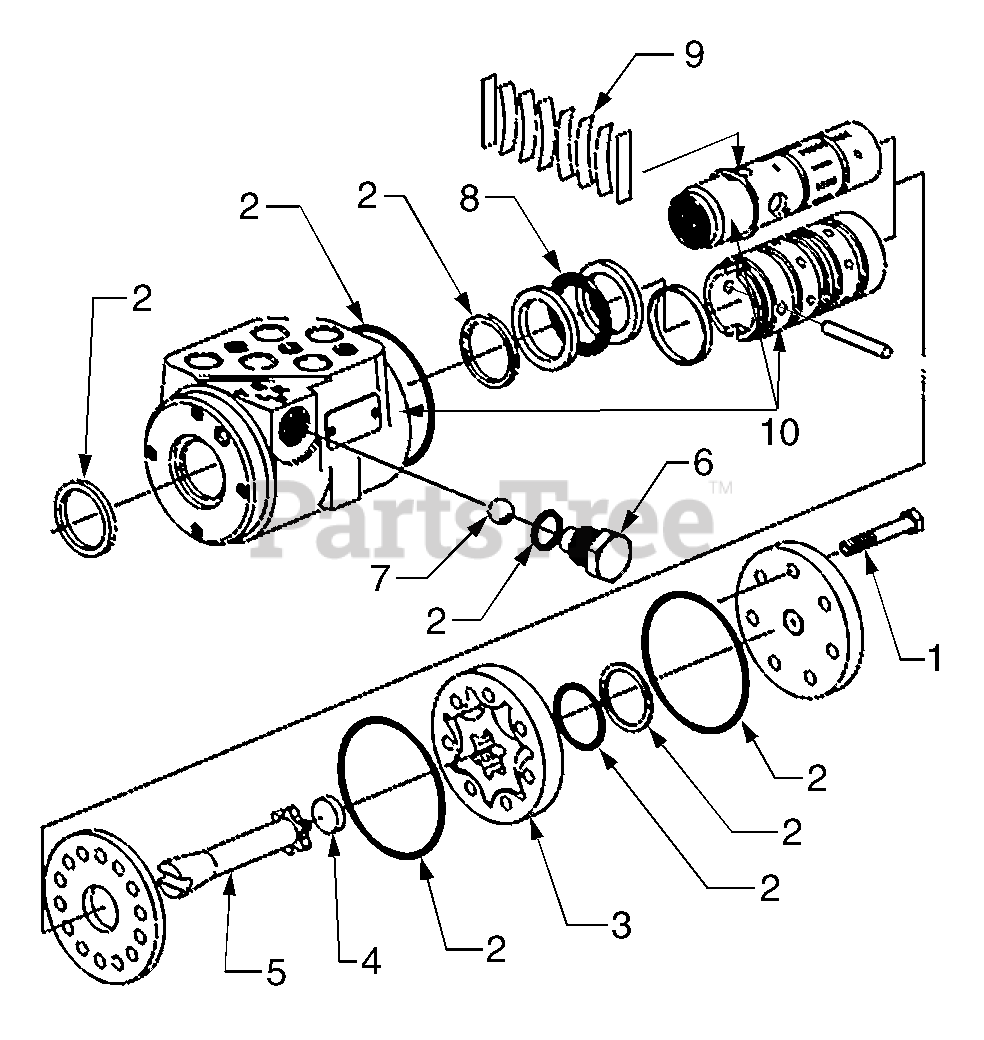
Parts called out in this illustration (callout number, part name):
1	Screw, Hex Cap, 1.57" Lg.
2	Seal Kit
3	Gerotor Assembly
4	Spacer, .240 Lg.
6	Plug, Manual Check
7	Ball, Manual Check
9	Spring Kit, Centering
10	Spool, Sleeve and Housing
